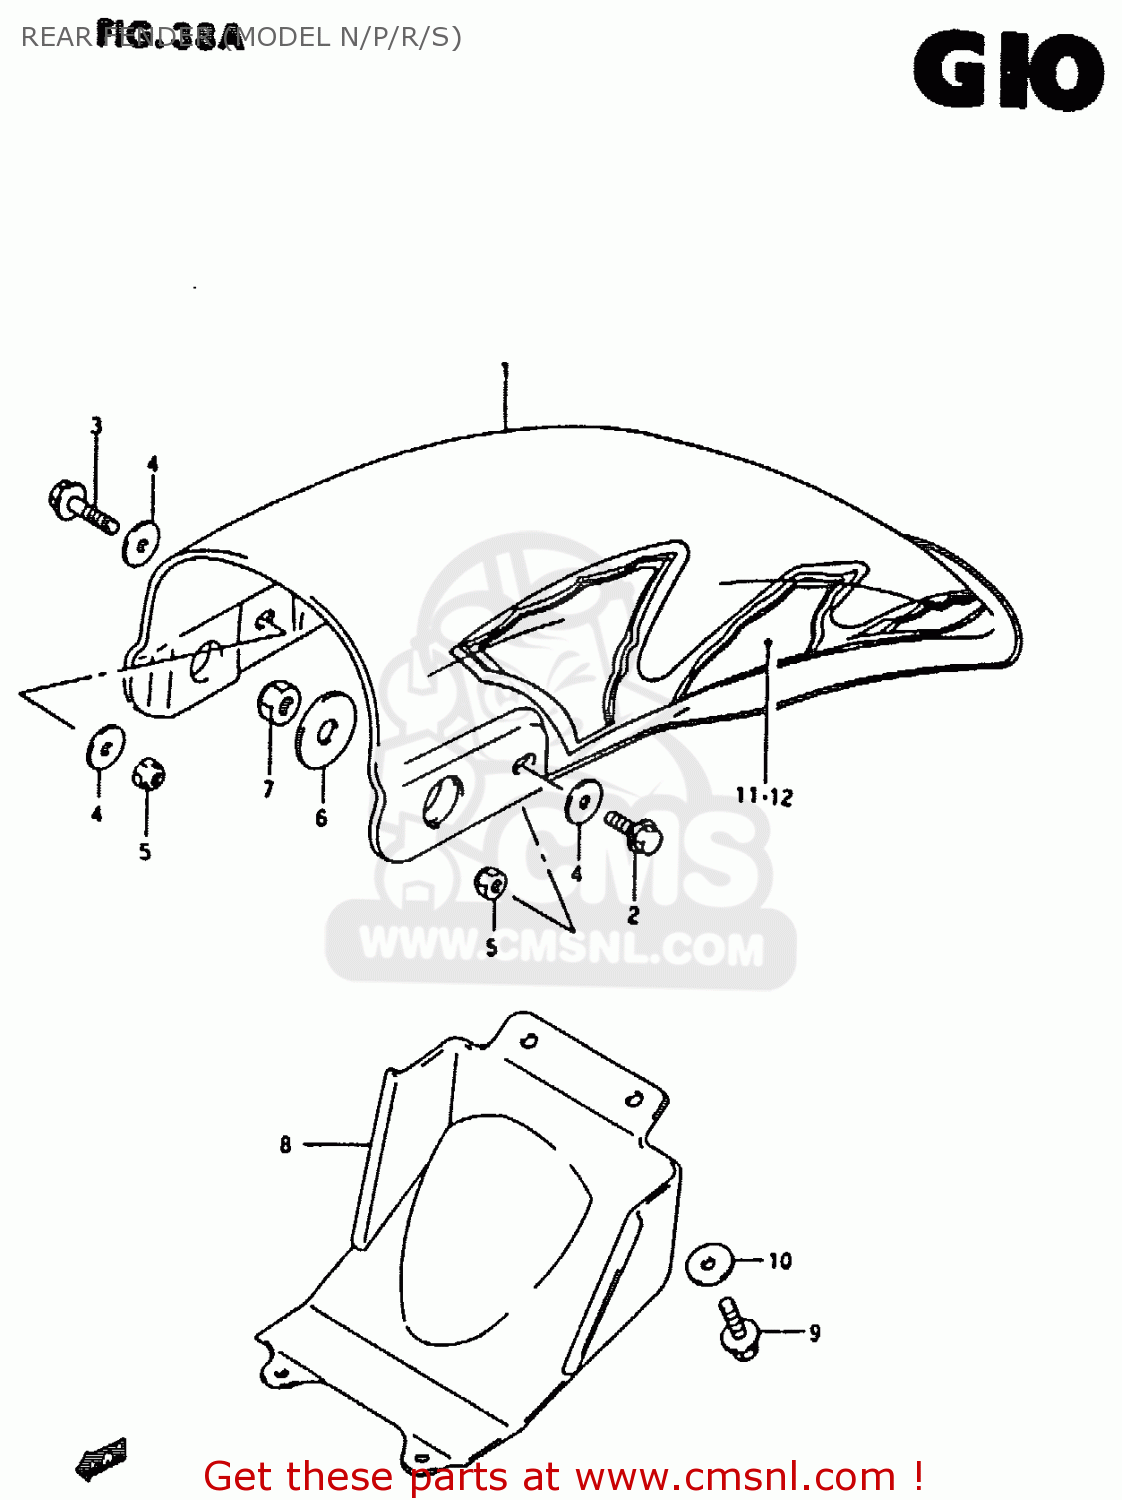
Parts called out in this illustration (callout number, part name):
1	FENDER,RR
2	BOLT
3	BOLT
4	WASHER(6.5X20X1.6)
5	NUT
6	WASHER (10.5X30X2.3)
7	NUT
8	MUDGUARD,RR FENDER FR
9	BOLT
10	WASHER
11	EMBLEM, REAR FENDER RH
12	EMBLEM, REAR FENDER LH
